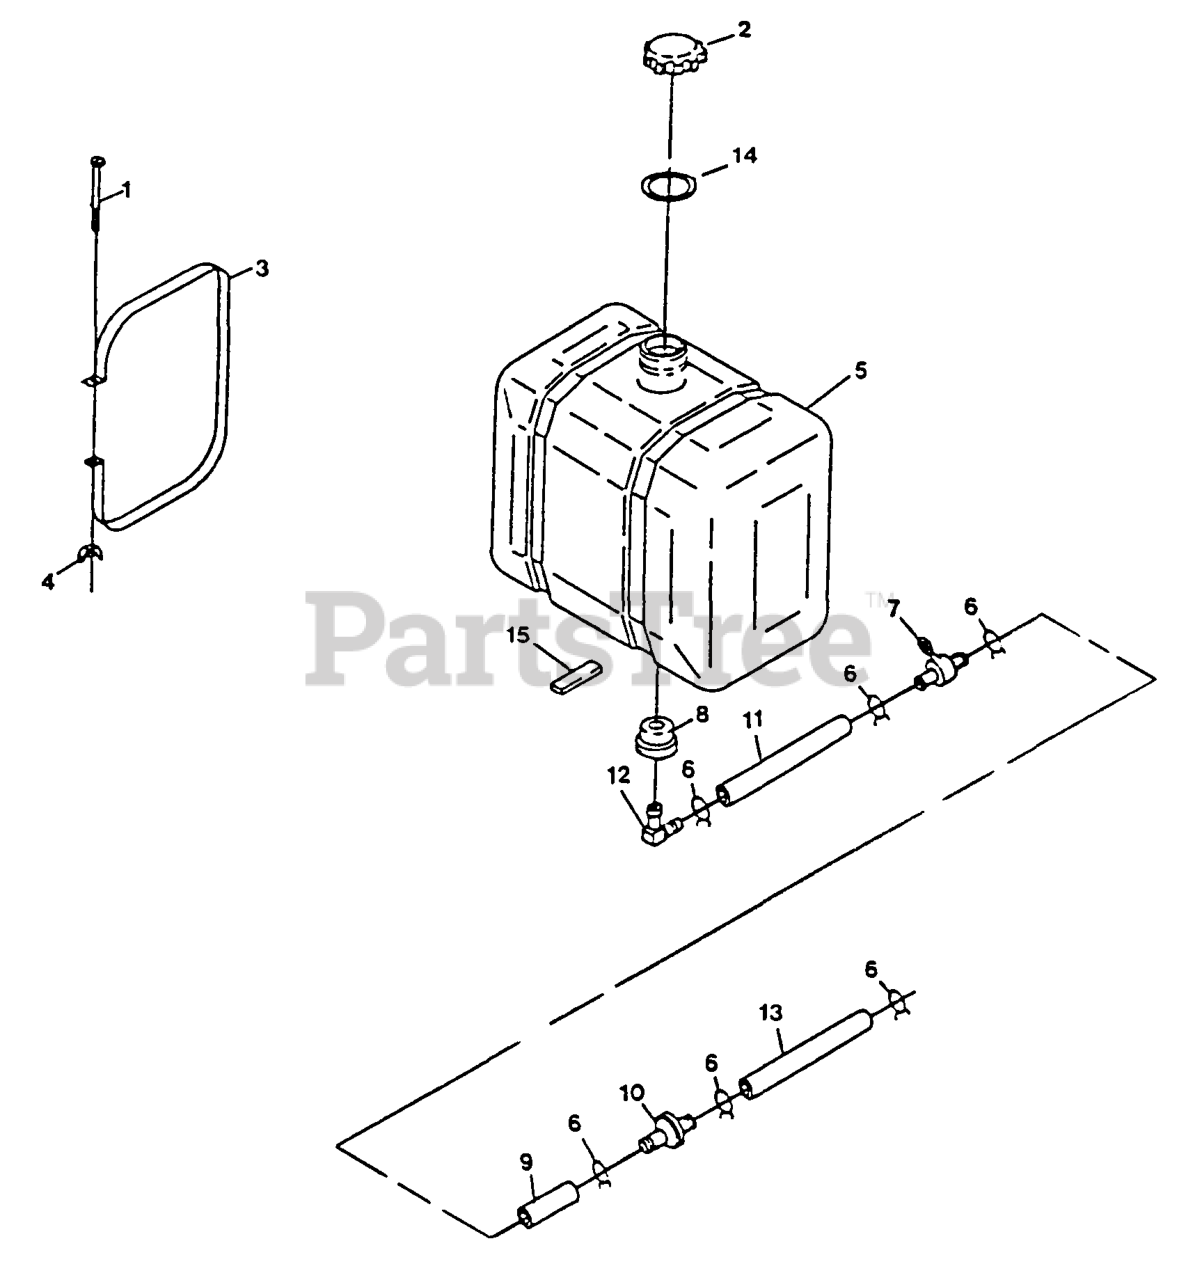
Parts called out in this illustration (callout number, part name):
1	SCRW,MACH CRPH
2	CAP-FUEL
4	WINGNUT
7	VALVE-FUEL
9	HOSE-LINE, FUEL
12	ELBOW-TANK, FUEL
15	PAD,PLASTIC TANK
